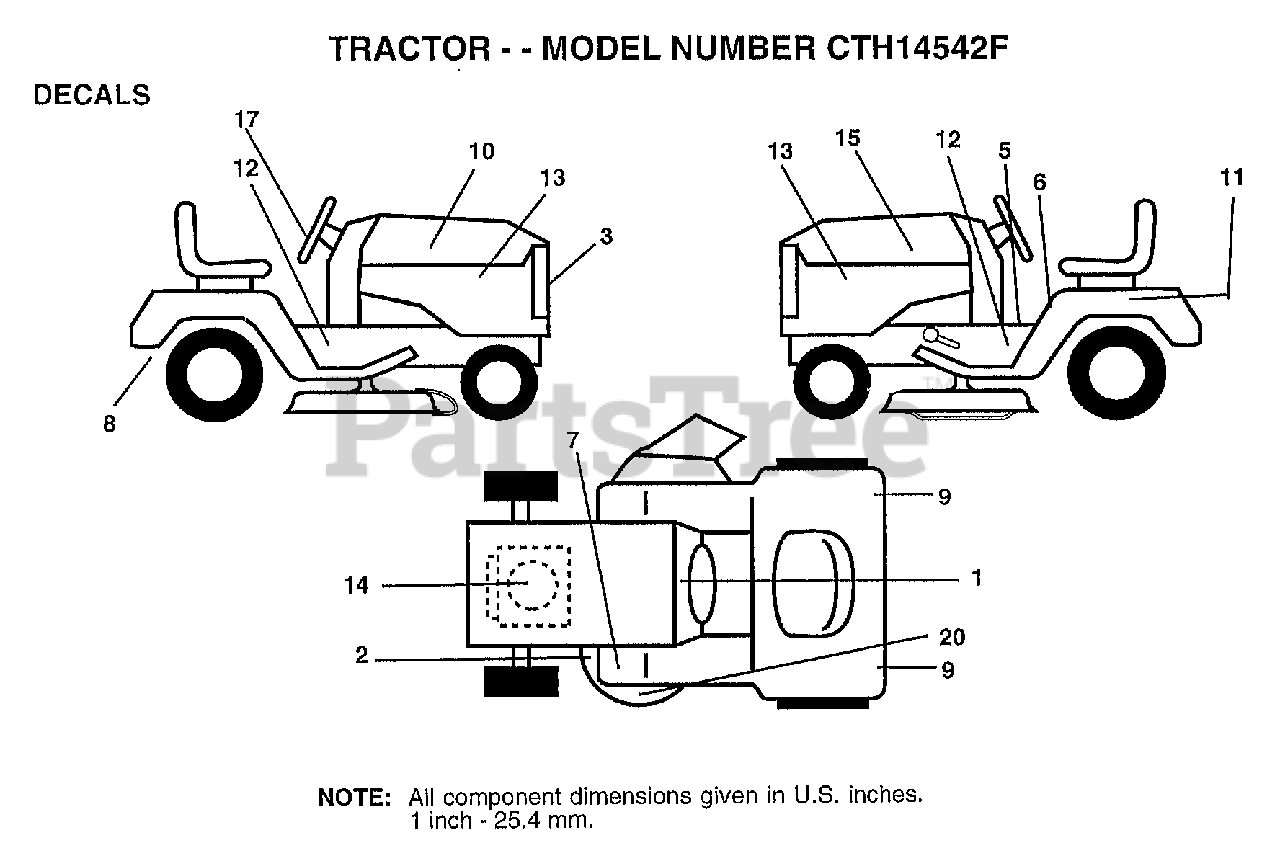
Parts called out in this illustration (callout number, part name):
1	"DECAL-INST,OPER"
2	DECAL
3	DECAL GRILLE
5	DECAL BRAK PARK
6	"DECAL DANGER,FEND"
8	DECAL DRAWBAR LH
9	REFLECTOR-TAIL YT
10	DECAL HOOD RH
11	DECAL.BATRY.3-3908
12	"DECAL CHASSIS 42"""
13	DECAL SIDE PANEL
14	DECAL, ENGINE
15	DECAL HOOD LH
17	DECAL INST STG WH
20	"DECAL,ENVIRO DECK"
